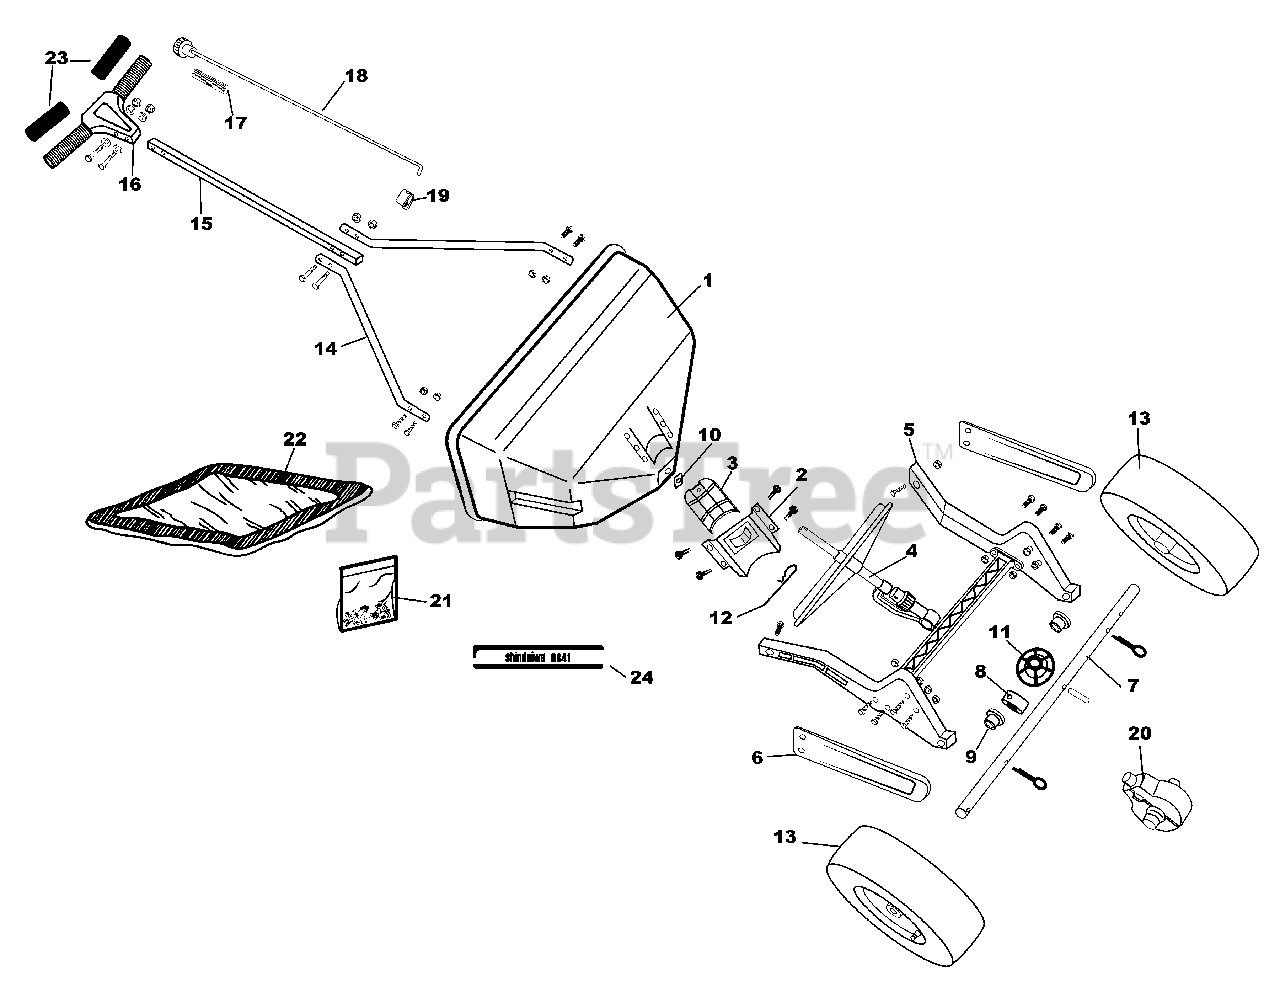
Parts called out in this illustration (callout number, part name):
1	Hopper Assembly
2	RATE CAM & CHUTE ASSEMBLY
3	SHUTOFF PLATE
4	Impeller Assembly
5	Frame Assembly
8	AXLE COLLAR
9	Axle Bushings
10	IMPELLER SHAFT BEARING
11	Axle Gear
12	AGITATOR
13	Drive & Free Turning Wheels
14	HANDLE BRACES
15	HANDLE TUBE
16	T-HANDLE ASSEMBLY
17	CONTROL KNOB SPRING
18	Control Knob & Wire Ass'y.
19	WIRE RETAINING CLIP
20	GEAR COVER ASSEMBLY
21	FASTENER PACKAGE
22	Hopper Cover
23	Handle Grip
24	Hopper Label
